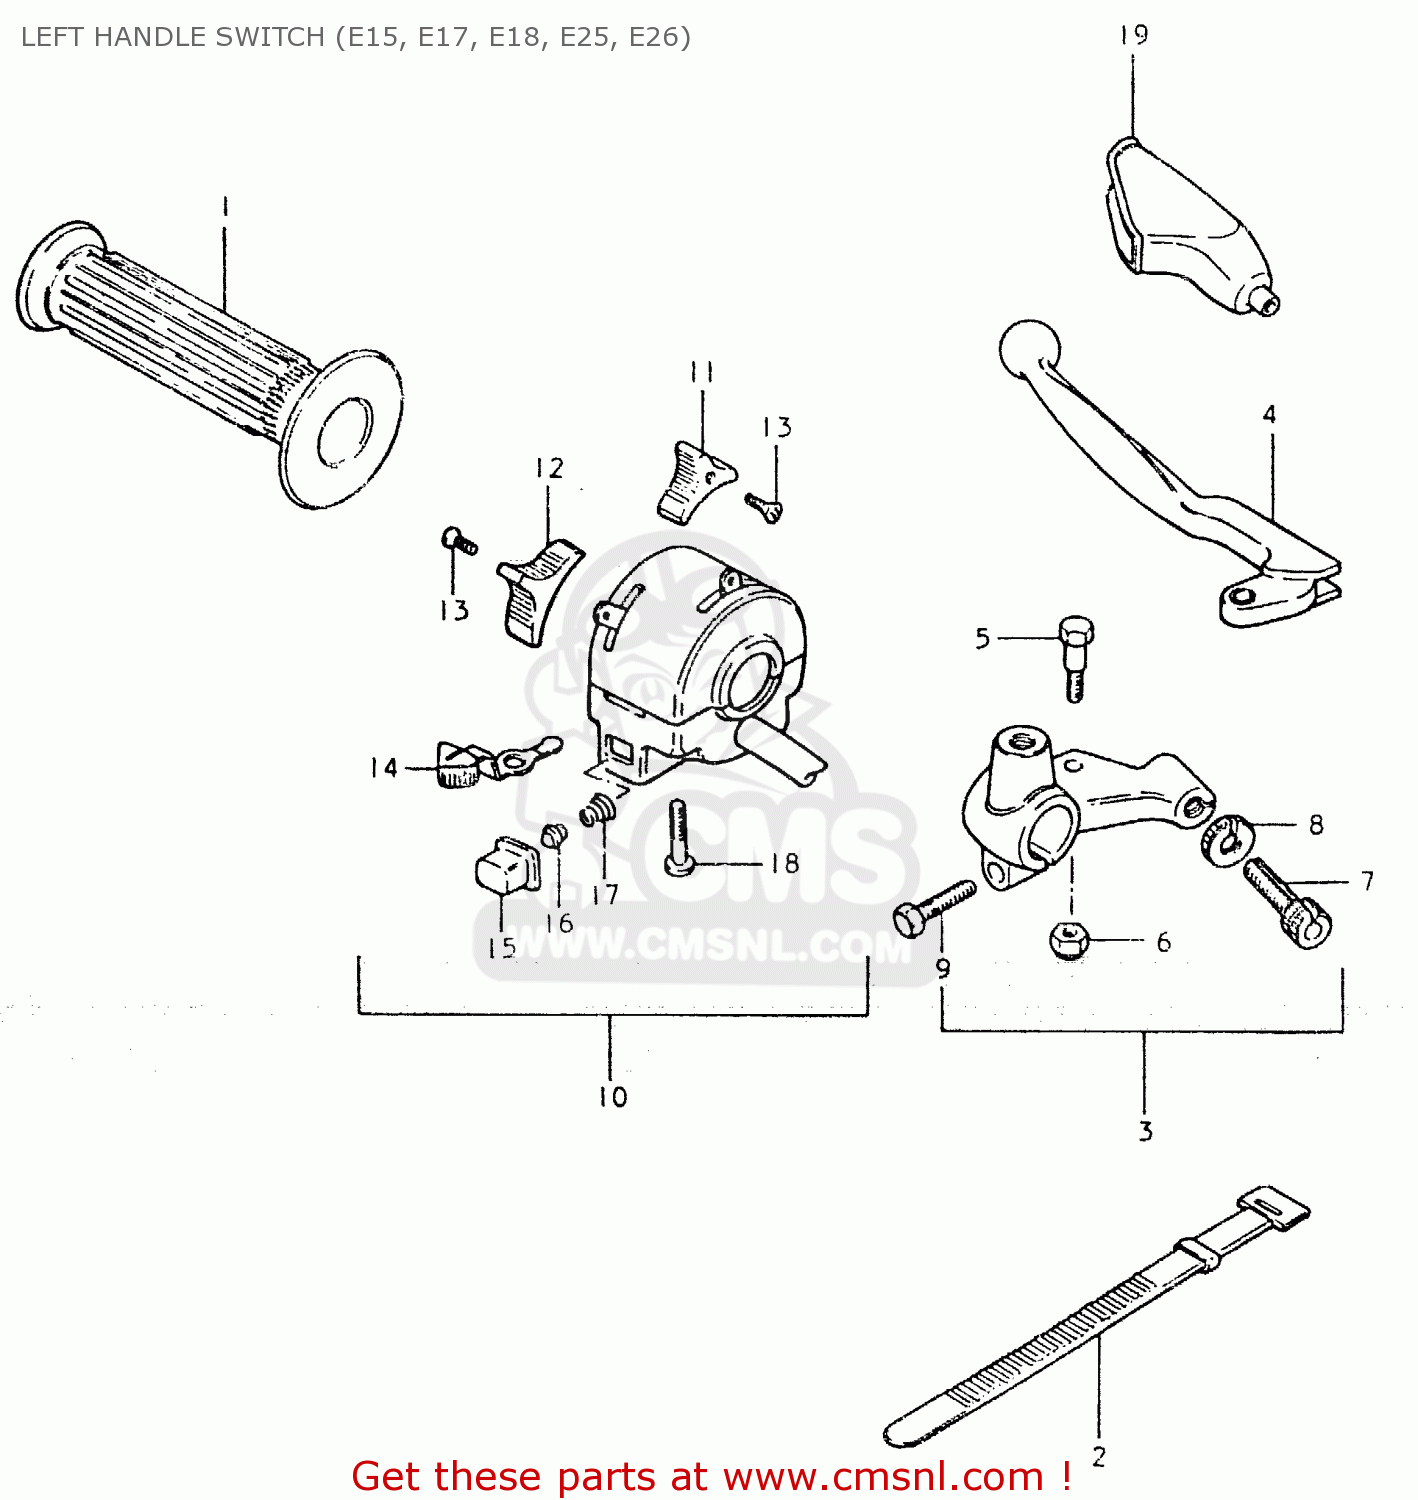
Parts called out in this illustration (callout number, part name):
1	GRIP,L
2	CLAMP(L:120)
3	LEVER ASSY,CLUTCH
4	LEVER,CLUTCH
5	BOLT,LEVER
6	NUT 6MM
7	ADJUSTER,CABLE
8	NUT,CABLE ADJUSTER
9	BOLT
10	SWITCH ASSY, HANDLE LH
11	KNOB,LIGHTING SWITCH
12	KNOB,DIMMER SWITCH
13	SCREW
14	KNOB,TURNSIGNAL
15	BUTTON,HORN
16	CONTACT
17	SPRING
18	SCREW
19	COVER,CLUTCH LEVER
